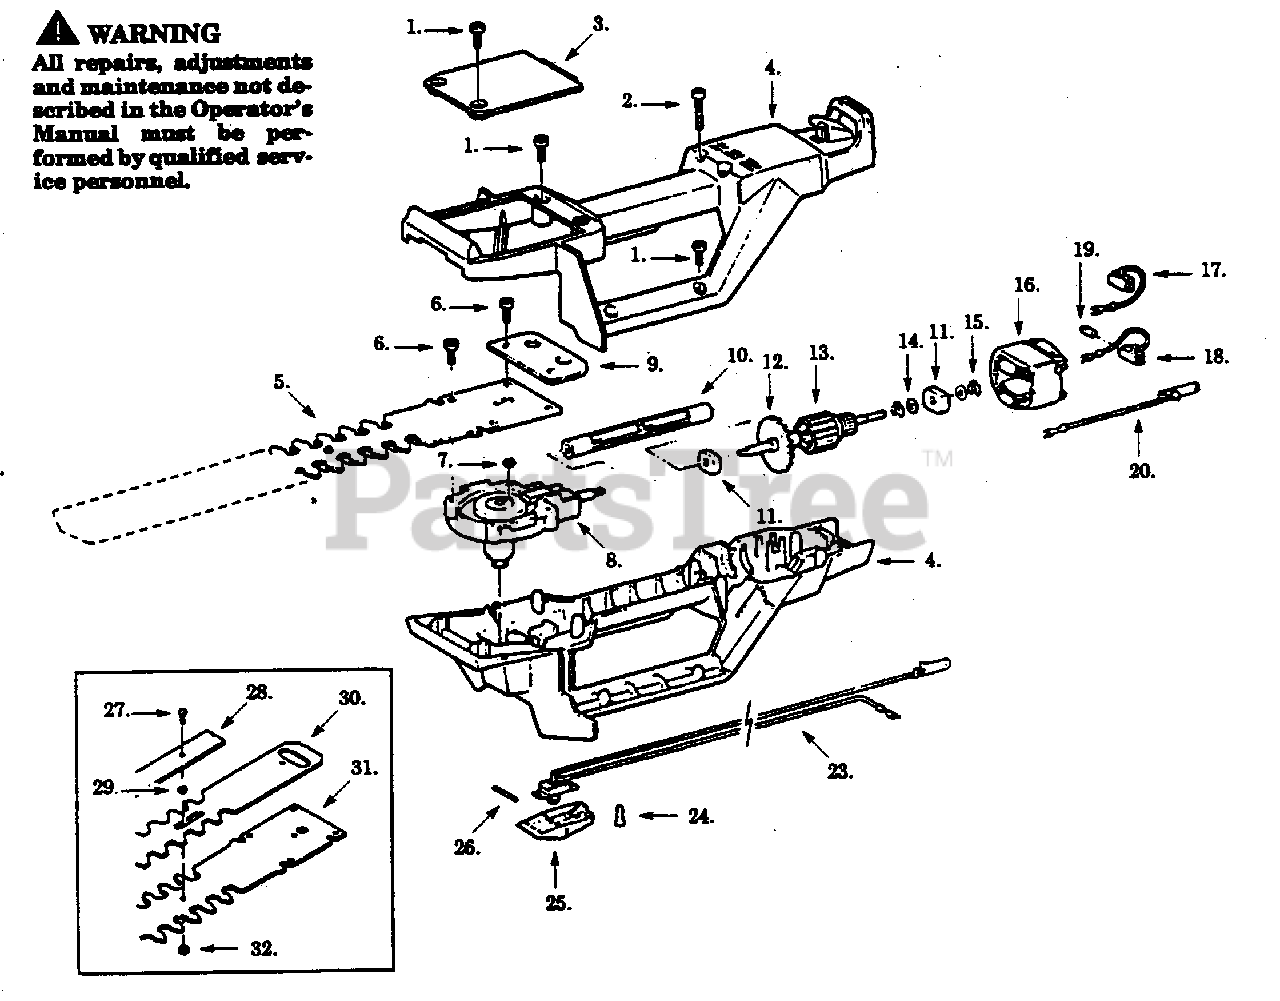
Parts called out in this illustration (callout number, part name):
3	Gear Box Cover
4	Housing Set
5	Blade Ass'y.-14"
5	Blade Ass'y.-17"
5	Blade Ass'y.-19"
5	Blade Ass'y.-22"
8	Gear Box Ass'y.
10	Drive Shaft
12	Impeller Fan
13	Armature/Fan Ass'y.
15	Retaining Ring
16	Field Ass'y.
17	Brush Holder/Wire Ass'y.
18	Brush Holder/Wire Ass'y.
20	Lead Wire Ass'y.
23	Switch/Wire Terminal Ass'y.
25	Switch Cap
26	Groove Pin
28	Retaining Plate-14"
28	Retaining Plate-17"
28	Retaining Plate-19"
28	Retaining Plate-22"
30	Cutting Blade-14"
30	Cutting Blade-17"
30	Cutting Blade-19"
30	Cutting Blade-22"
31	Stationary Blade-14"
31	Stationary Blade-17"
31	Stationary Blade-19"
31	Stationary Blade-22"
